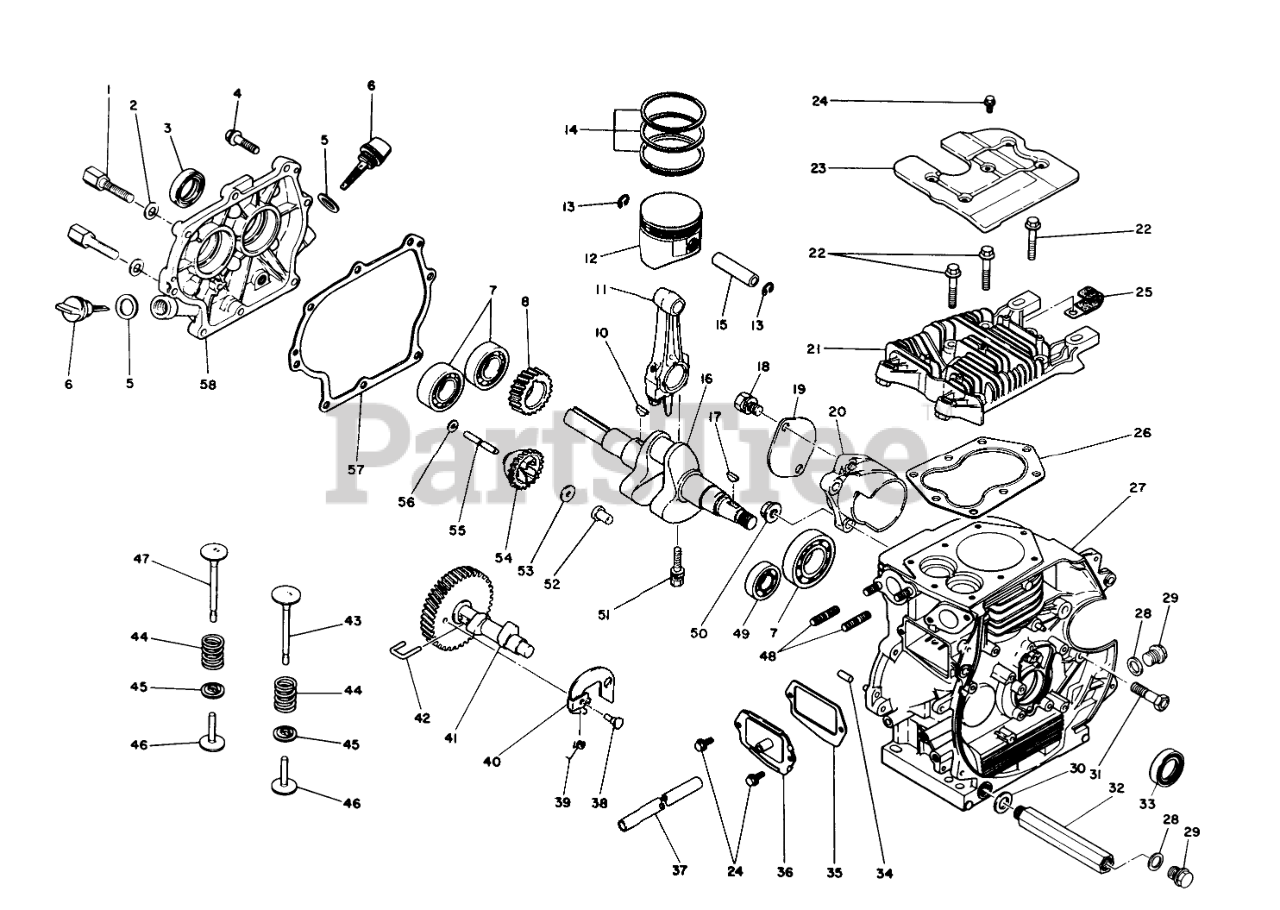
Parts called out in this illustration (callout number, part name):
2	WASHER
3	OIL SEAL
5	GASKET
6	Gauge-Oil (Incl. Ref. #5)
7	BEARING
8	CRANKSHAFT GEAR
11	Connecting Rod Assembly (Std.)(Incl. Ref #51)
12	Piston Assembly (Std.)(Incl. Ref. #15)
13	PISTON PIN CLIP
14	PISTON RING SET
15	PISTON PIN
16	CRANKSHAFT
18	BOLT & WASHER
19	COVER
20	BRACKET
21	CYLINDER HEAD
23	COVER-HEAD
25	CLAMP
26	HEAD GASKET
27	Cylinder Block Assembly (Incl. Ref. #34 & 48)
28	GASKET
29	DRAIN PLUG
30	GASKET
32	NIPPLE
33	OIL SEAL
35	GASKET=BRTHR
36	BREATHER VALVE ASM
37	BREATHER TUBE
39	SPRING
40	FLYWEIGHT
41	Camshaft Assembly (Incl. Ref. #38, 39, 40 & 42)
43	INT VALVE
44	VALVE SPRING
45	RETAINER VALVE
46	TAPPET
47	EXHAUST VALVE
49	BEARING
50	Nut-Flange
51	CONNECTING ROD BOLT
52	SLIDER-GOV
53	SPACER
54	Governor Gear Assembly (Incl. Ref. #52)
55	SHAFT-GOV.
56	WASHER
57	CRANKCASE GASKET
58	CRANKCASE COVER
